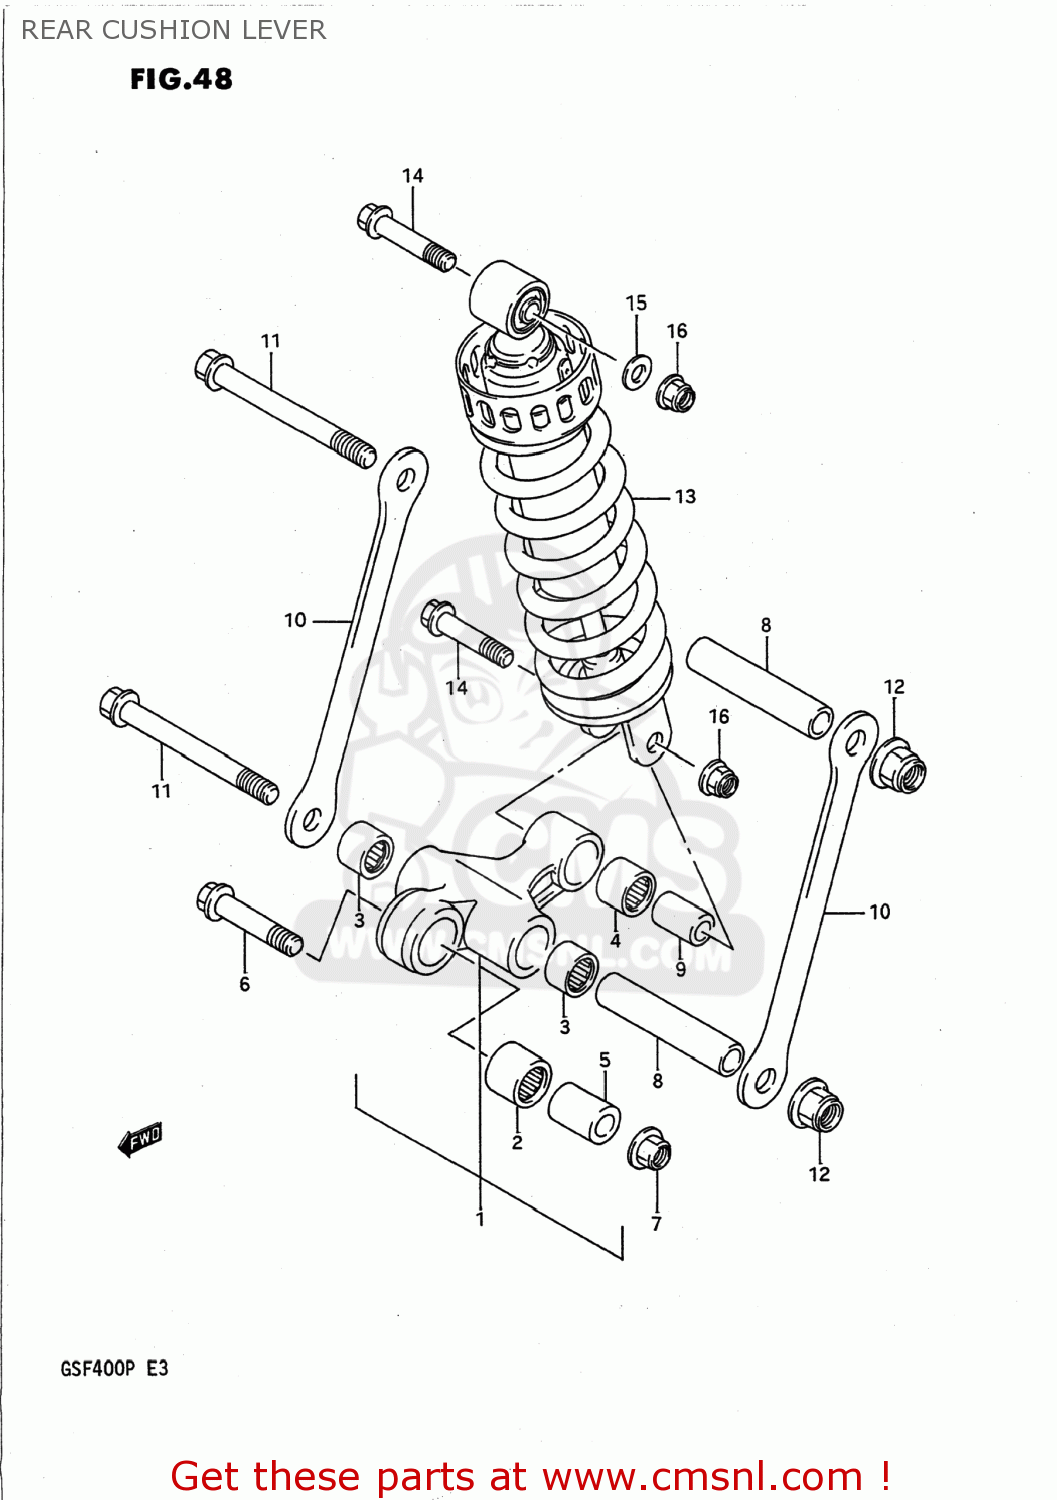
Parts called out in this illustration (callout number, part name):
1	LEVER SET,RR CUSHION
2	BEARING(20X27X26)
3	BEARING(17X24X25)
4	BEARING(17X24X26)
5	SPACER,REAR CUSHION LEVER
6	BOLT
7	NUT 12MM
8	SPACER(12X17X85)
9	SPACER,RR CUSHION LEVER
10	ROD,RR CUSHION LEVER
11	BOLT(12X115)
12	NUT 12MM
13	ABSORBER ASSEMBLY,REAR SHOCK
14	BOLT(10X52)
15	WASHER 10MM
16	NUT 10MM
